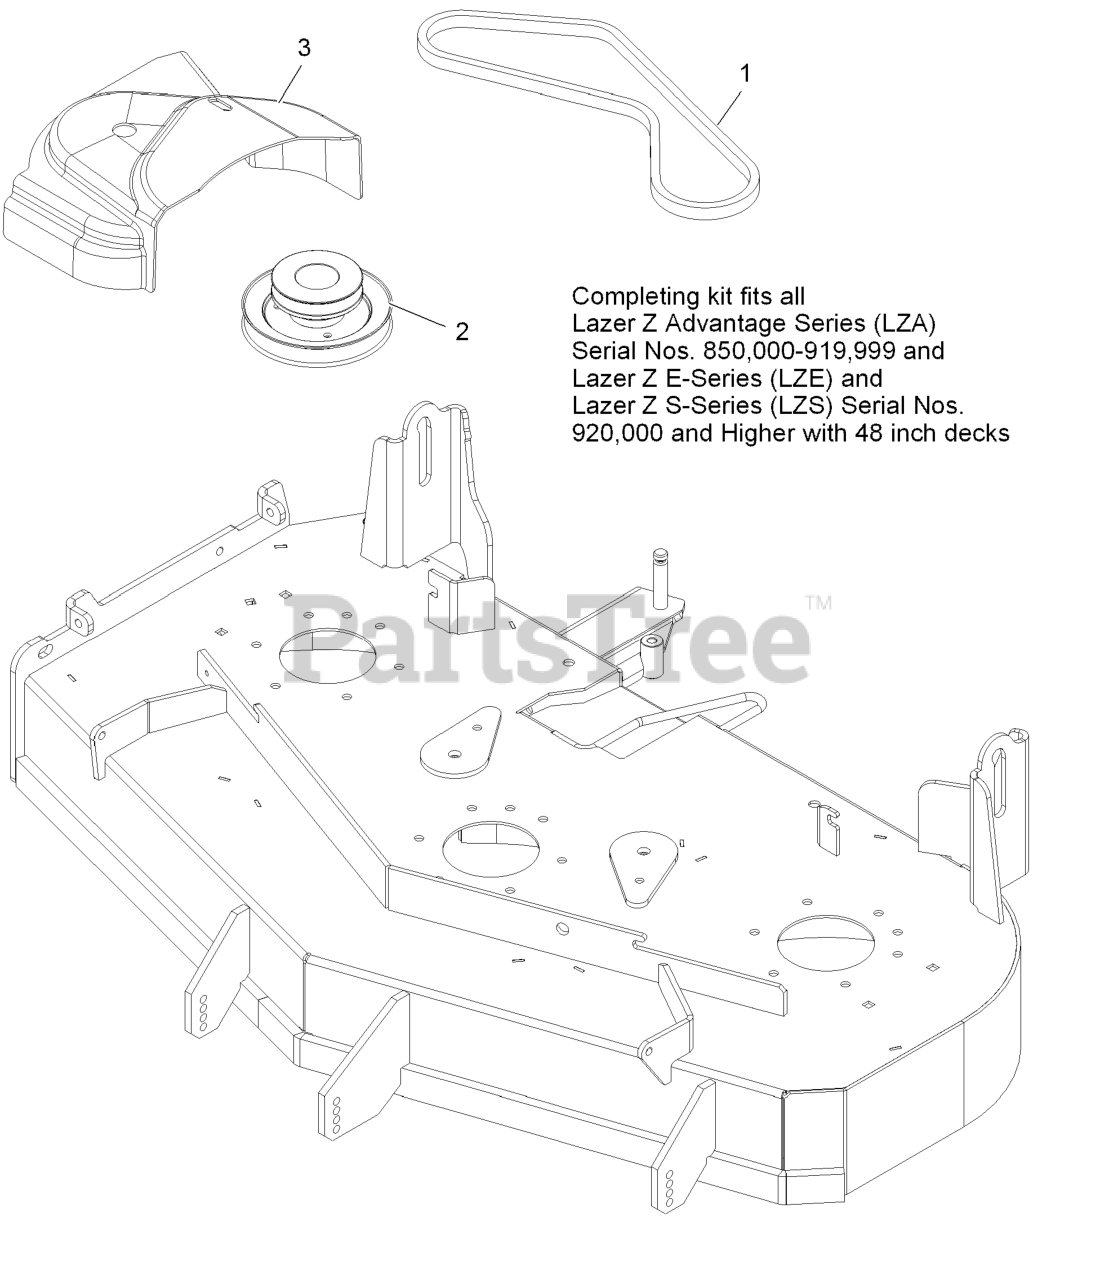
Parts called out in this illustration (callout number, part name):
1	Belt, Blower (48")
2	Jackshaft-Uv Drive, 484 Splined
3	Cover,Belt Uv 48
